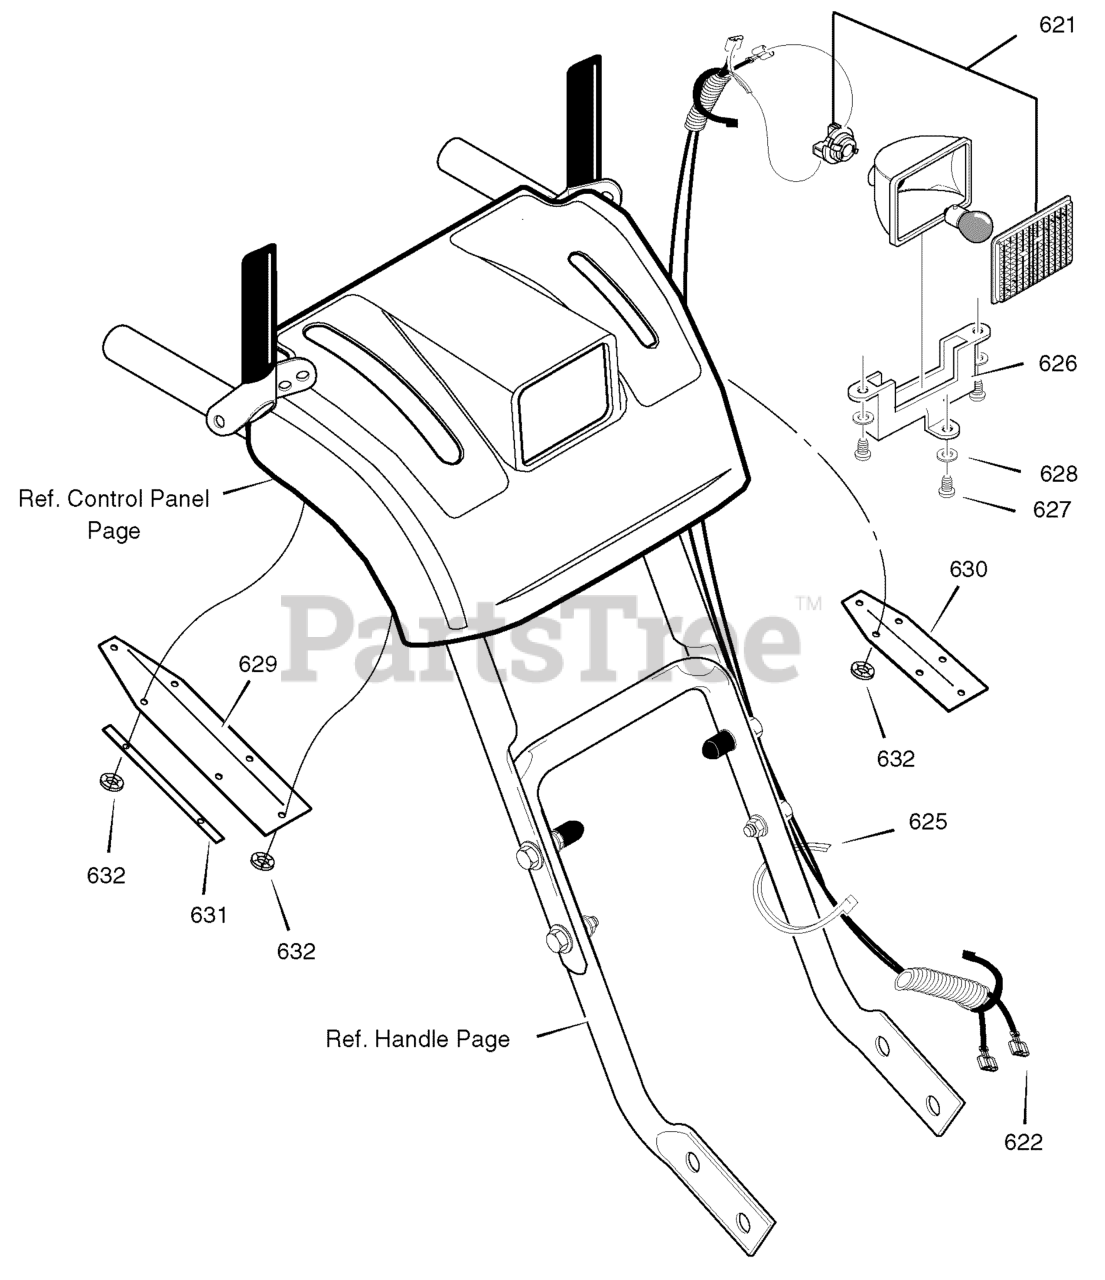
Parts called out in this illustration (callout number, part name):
621	LIGHT, HALOGEN
622	HARNESS, WIRE
625	TIE, CABLE
626	BRACKET, LIGHT
627	SCREW #8 X .50
628	WASHER, FLAT
632	NUT, PUSH
